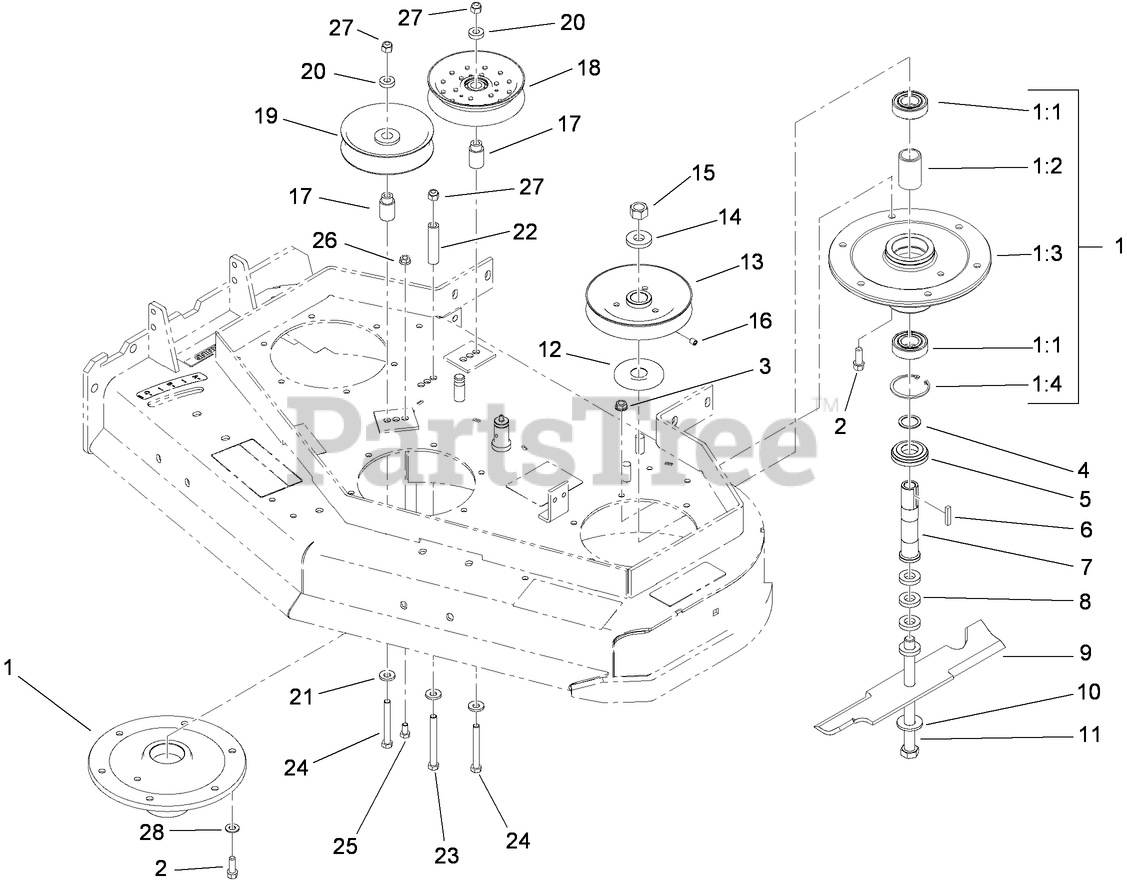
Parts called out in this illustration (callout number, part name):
1	SPINDLE HOUSING ASM
1:1	BEARING
1:2	SPACER-BEARING
1:3	HOUSING-SPINDLE
1:4	RING-SNAP
2	SCREW-HWH
3	NUT-HHF, WHIZ
4	WASHER-SPACER
5	SPACER-GUARD, BOTTOM
7	TUBE-SPINDLE, SHORT
8	SPACER
9	BLADE-14 INCH (HIGH SAIL)
10	WASHER-SPRING
11	SCREW-CAP, HH
12	Guard-Bearing, Top
13	SHEAVE
14	WASHER-RETAINER, SHEAVE
15	NUT-HEX
16	SCREW-SET
17	BUSHING-IDLER
18	IDLER-PULLEY, FLAT
19	PULLEY-IDLER
20	SPACER
21	WASHER-BELLEVILLE
22	SPACER
23	SCREW-HH
24	SCREW-HH
25	SCREW-HH
26	NUT-HF
27	NUT-LOCK, NI
28	WASHER-FLAT
